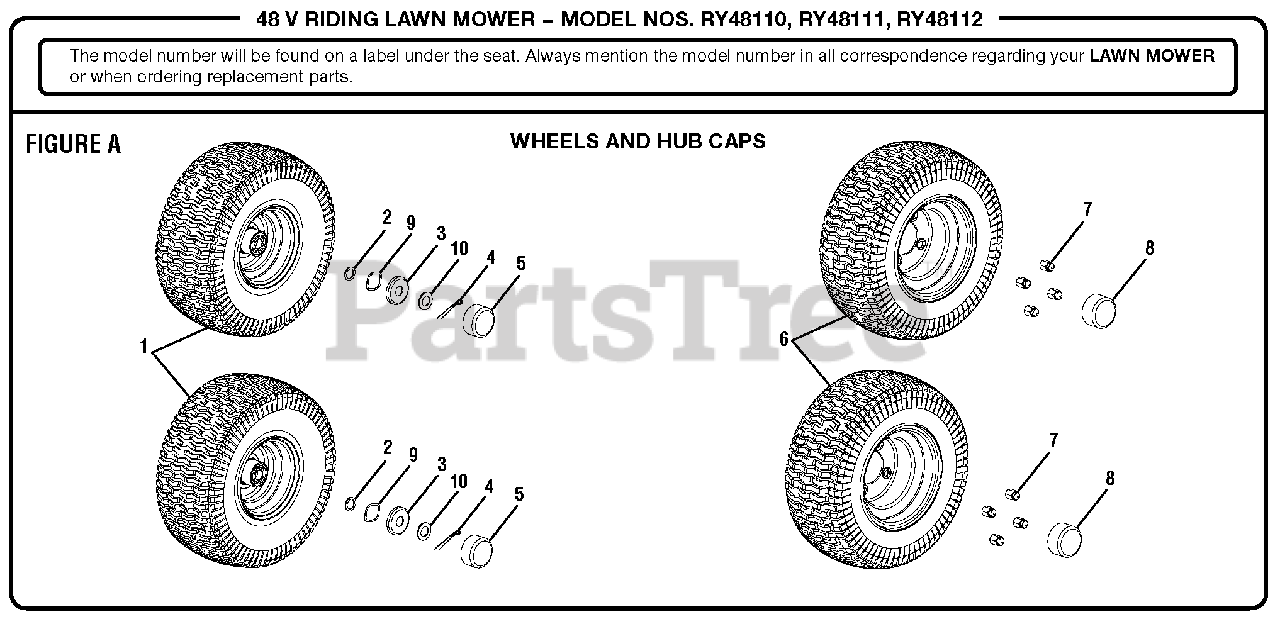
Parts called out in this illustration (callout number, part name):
1	Front Wheel Assembly
2	Washer (OD28 x ID20.5 x 2t)
3	Front Wheel Bearing Cover
4	Cotter Pin (4 x 40 mm)
5	Dust Cover, Front Wheel
6	Rear Wheel Assembly
7	Acorn Nut (M14)
8	Wheel Hub Cover
9	Wavy Washer
10	Washer (OD37 x ID21 x 0.3t)
